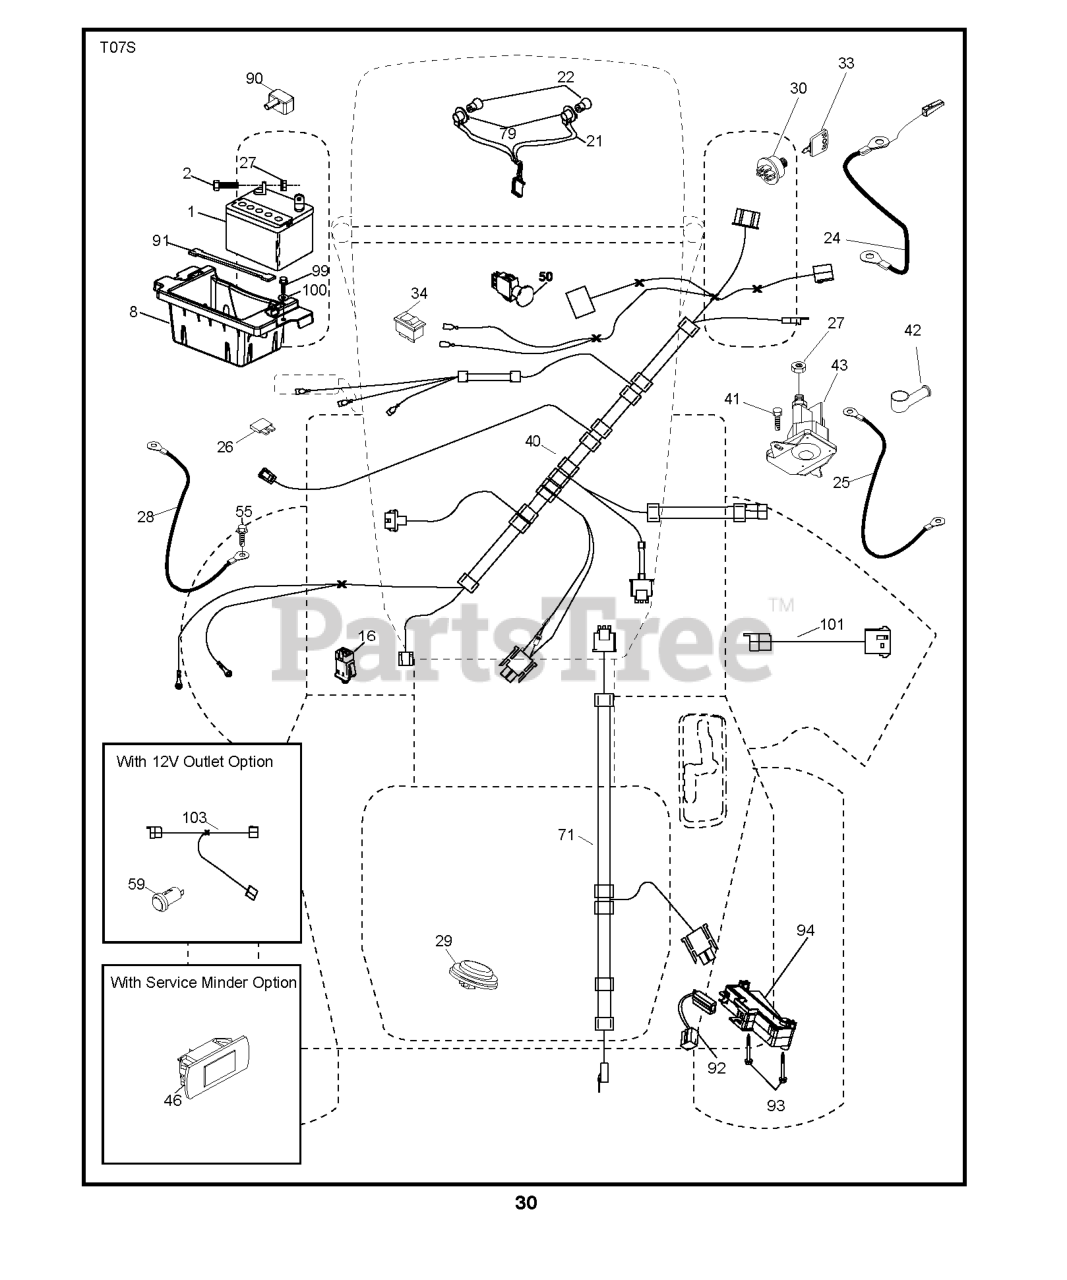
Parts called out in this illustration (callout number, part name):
1	BATTERY 12V .35 AMP
2	BOLT.HEX.1/4.X.3/4.DICHROMATE
8	BOX.BATTERY.MOUNT.FRONT.LT
16	SWITCH INTERLOOK PUSH-IN
21	HARNESS ASSY LIGHT
24	CABLE.BATT.POS.WIRE.TG.DA SOL
25	CABLE.STARTER.6G.BL/RED.17.5
26	FUSE 20AMP
27	NUT
28	CABLE GROUND 6 GA 21" 90T BLK
29	SWITCH.SEAT.DELTA.OPC.
30	SWITCH.IGN.DELTA.W.LGH.ROS
33	KEY.CHAIN.BLISTER.PACK.GEN.INT
40	HARNESS.IGN.DASH.HUQ/P
41	SCREW
42	TERMINAL COVER
43	SOLENOID.W/BRASS.PLUNGER
46	RP.GUAGE.SRVCMNDR.HRMTR.
50	RP.PTO.SWITCH.8 TERMINAL.BLACK
55	SCREW 5/16"
59	OUTLET.12-VOLT
71	HARNESS-CHASSIS SUB
79	BULB HOLDER ASM.
90	COVER.TERMINAL.BATTERY
91	STRAP.BATTERY.MOUNT.FRONT(2 2)
92	HARNESS.PIGTAIL.CONSLE
93	SCREW.PLASTITE
94	MODULE.REVERSE.ROS
99	SCREW HEXWSHR 1/4-20X3/4
102	PIGTAIL.MATNLK.NEW.HAR
103	HARNESS PIGTAIL 12V OUTLET
